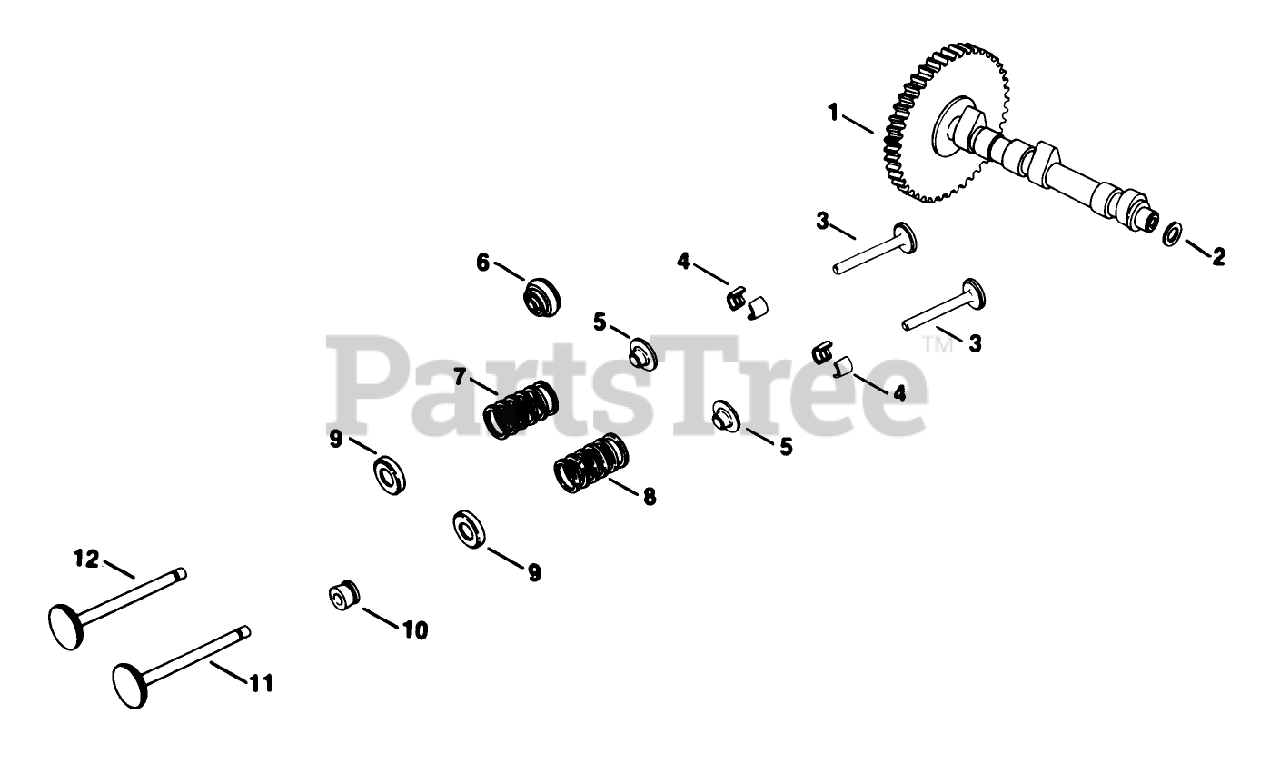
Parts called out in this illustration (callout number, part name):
1	Camshaft
2	Spacer-Camshaft
3	Tappet
4	Kit-Retainer
5	Retainer-Spring
6	Rotator
7	Spring Exhaust Valve
8	Spring, Valve
9	Retainer-Spring
10	Seal-Intake Valve Stem
11	Valve-Intake
12	Valve-Exhaust
